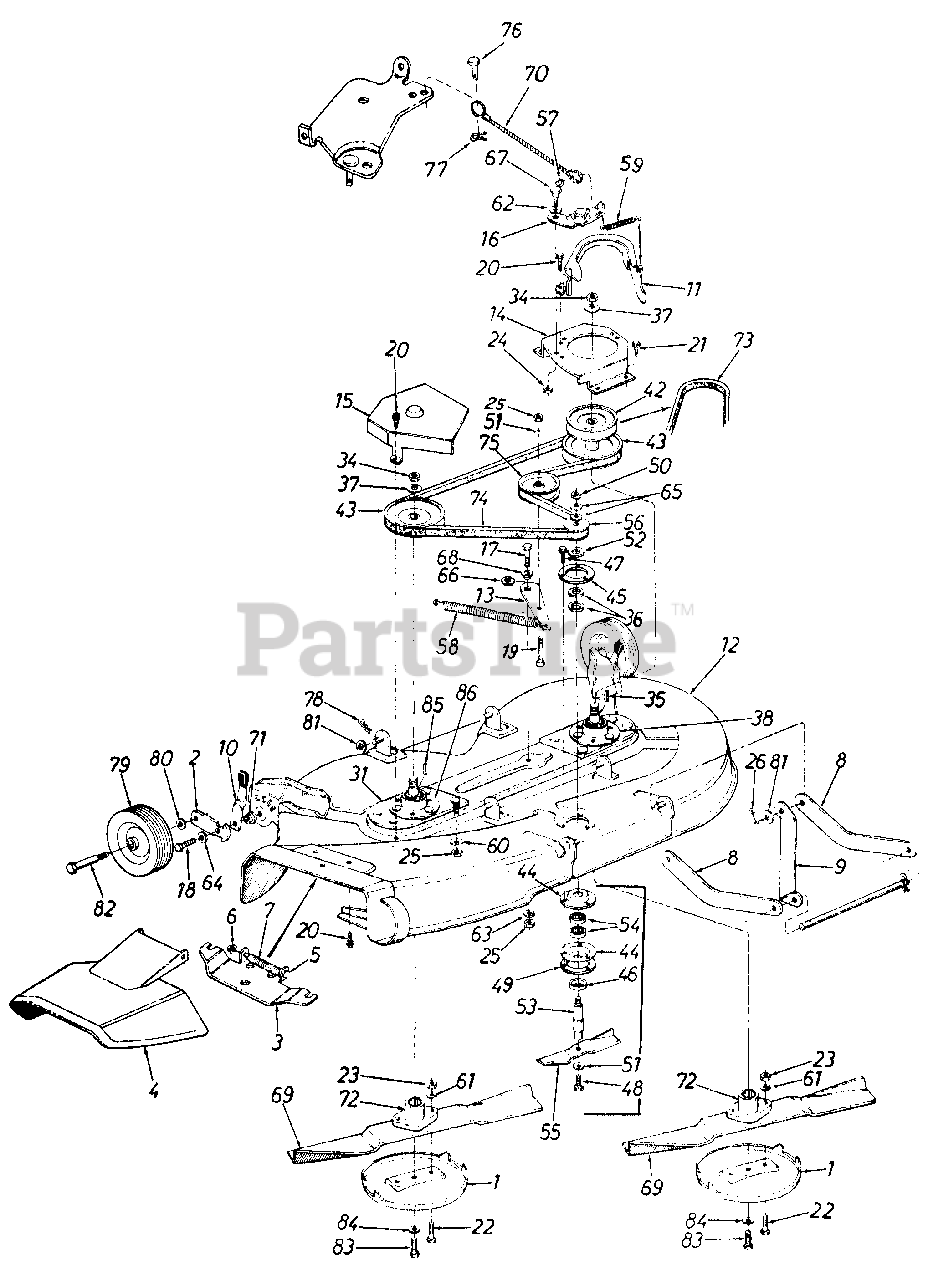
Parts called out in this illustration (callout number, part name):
1	Anti-Scalp Plate
2	Wheel Pivot Bar
4	Chute Cover Ass'y.
6	Cap Speed Nut 1/4" Rod.
7	Torsion Spring
11	Belt Guard
12	44" Deck Ass'y.
13	Idler Bracket
14	Pulley Cover-L.H.
17	Hex Bolt 3/8-24 x 1.00"*
18	Hex Bolt 3/8-24 x 1.25"Lg.*
19	Hex Bolt 3/8-24 x 1.50"*
20	Hex Wash. S-Tapp Scr.1/4-20 x .50"*
21	Hex Wash. Hd. Tapp Scr. 5/16-18 x .75" Lg.
22	Hex Bolt 5/16-24 x 1.25" (Grade 5)
23	Hex Nut 5/16-24 Thd.*
24	Hex Cent. L.-Nut 5/16-18 0 Thd.
25	Hex Nut 3/8-24 Thd.*
26	Cotter Pin 3/32 Dia. x 1.00" Lg.*
34	Hex Jam Nut 5/8-18 Thd.
35	Square Key 3/16 x 2.25" Lg.
36	Fl. Wash. 5/8" I.D. x 15/16" O.D.
37	Bell. Wash. .630 I.D. x 1.25 x .090
38	L.H. Blade Spindle Ass'y. Comp.
42	5/8 "V"Pulley .79 I.D. x 5.75 O.D.
43	"V"Pulley .79 I.D. x 6.50 0 O.D.
44	1-3/8" I.D.-Bearing Housing
45	Reinforcement Plate
46	Bearing Shield
47	Hex "B" Tap Scr. .250" x, 1.0" Lg.
48	Hex Cl.-Scr. 3/8-24 x .88 0 Lg.
49	Reinforcement Plate
50	Hex Jam Nut 1/2-20 Thd
51	Bell.-Wash. .400 I.D. x .88 0 O.D. x .060
52	Fl.-Wash. .635 x 1.04 O.D. x .1 20"
53	6.5" Blade Spindle
54	Ball Brg. .62 I.D. x 1.30" O.D. x 44"
56	1/2" V-Pulley Half .625 I.D. x 2.25" O.D.
57	Cap Speed Nut 1/4" Rod.
58	Extension Spring .73 O.D. x 4.31 Lg.
59	Extension Spring
60	Bell.-Wash. .400 I.D. x .88 0 O.D. x .060
61	L.-Wash. 5/16" I.D.*
62	Spring Wash. .445 I.D. x .75 O.D. x .017
64	Bell.-Wash. .400 I.D. x 1.13 0 O.D. x .030
65	Bell.-Wash. .505 I.D. x 1.00 0 O.D. x .075
66	Spring Wash. .650 I.D. x .875 O.D. x .015 Thk.
67	Shld. Bolt .437 Dia. x .180
68	Shld. Spacer .625 I.D.
69	Mower Blade 21.88
70	Brake Cable Ass'y.
71	Shld. Spacer
72	Blade Adapter
73	"V"Belt 1/2 x 56" Lg.
74	"V"Belt 1/2 x 74" Lg.
75	Fl.-ldler w/Flanges 3.50 0 O.D.
76	Clevis Pin 1/4 Dia. x .53 0 Lg.
77	Intern. Cotter Pin 5/16" Dia.
78	Intern. Cotter Pin 1/2" Dia.
79	Deck Wheel 6 0 x 1.38
80	Bell.-Wash. .400 I.D. x .88 0 O.D. x .060
81	Fl.-Wash. .531 I.D. x .93 0 O.D. x .090
82	Shoulder Bolt 3/8-16 x 1.41
83	Hex Bolt 3/8-24 x .88" Lg.
84	L.-Washer 3/8 I.D.
85	Sq. Key 3/16 x .75" Lg.
86	R.H. Blade Spindle Ass'y. Comp.
